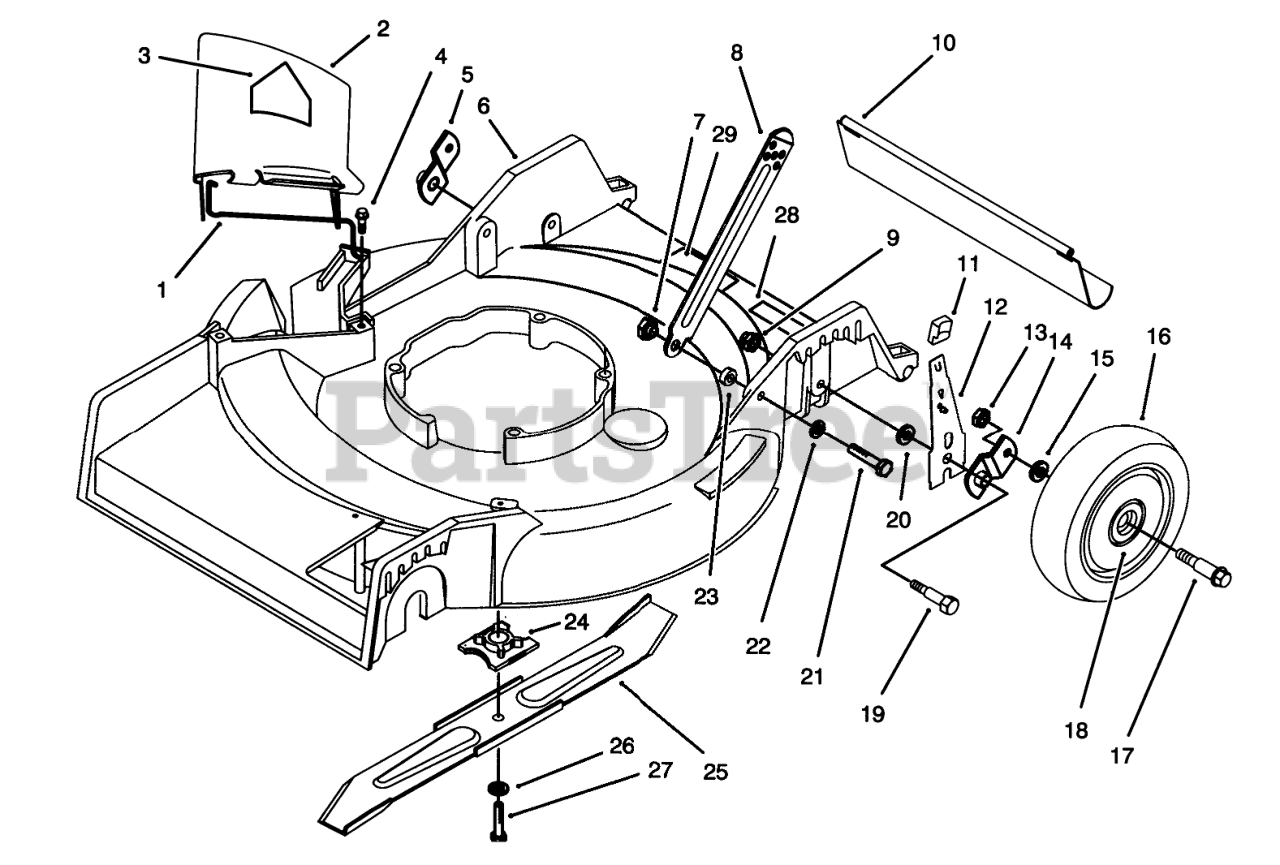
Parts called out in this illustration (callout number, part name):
1	SPRING HINGE
2	Deflector Assembly (Incl. Ref. #1 & 3)
3	DECAL-DANGER
4	SCREW-HWH
5	Pivot Arm
6	Housing Assembly (Incl. Ref. #28 & 29)
7	HANDLE PIVOT NUT
8	HANDLE LATCH
9	HANDLE PIVOT NUT
10	SHIELD - TRAILING
11	KNOB-ARM
12	REAR SPRING ARM ASM
13	NUT-LOCK
14	Pivot Arm
15	WASHER
16	Wheel & Tire Assembly (Incl. Ref. #18)
17	WHEEL BOLT
18	BUSHING
19	5/16-18 PIVOT SCREW
20	PIVOT WASHER
21	SCREW-HH
22	WASHER-LOCK
23	SPACER
24	BLADE RETAINER
25	Blade
26	WASHER-LOCK
27	SCREW-HH
28	DECAL-WARNING
29	DECAL-INSTRUCTION, SAFETY
